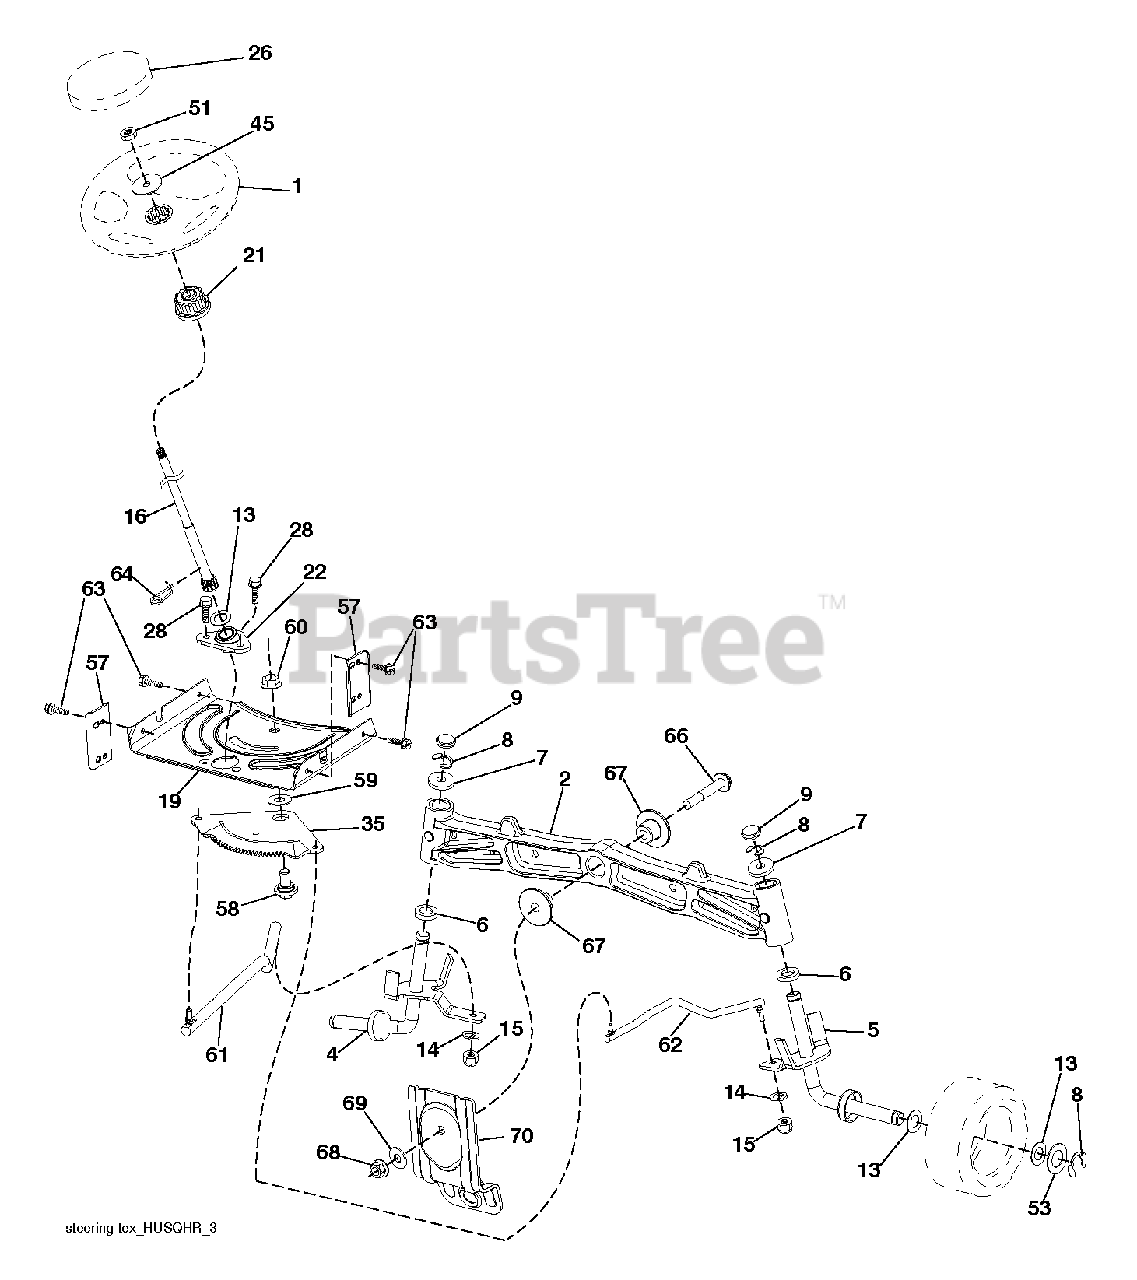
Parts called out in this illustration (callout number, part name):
1	WHEEL STEERING
2	AXLE.CAST.IRON
4	SPINDLE.WELDED.LH.15"TEX
5	SPINDLE.WELDED.RH.15"T
6	THRUST WASHER
9	CAP.SPINDLE.BLACK
14	WASHER, LOCK 3/8
15	NUT CROWNLOCK 3/8-24
16	SHAFT, STEERING
19	PLATE.STEER.DDL.NLT/NG
21	ADAPTER, WHEEL STNG..
22	STEERING.SUPT.LOWER.
26	RP INSERT.CAP.WHL.STRG.HUSQ.
28	SCREW, 3/8-16X3/4
35	GEAR.SECTOR.PLATE.DDL.
45	WASHER 9/16"ID, 2 3/8"OD
51	NUT.HEX.1/2-20
53	WASHER.HARDENED
57	BRACKET.UPSTOP.TEX
58	BOLT.SHOULDER.SECTOR.P
59	WASHER.THURST.SECTOR.S
60	NUT FLANGE LOCK 5/8-11
61	DRAGLINK.LH.BALLSTUD.D
62	DRAGLINK.RH.BALLSTUD.D
63	SCREW
64	RETAINER.CLIP.SPRING.S
66	BOLT HEX FGHD 7/16-14 X 3 SERR
67	BUSHING.PM.FRONT AXLE
68	NUT.LOCK.FLANGE.7/16
69	WASHER.1.5X.505X.118
70	BRKT.DECK.SUSPENSION.F
